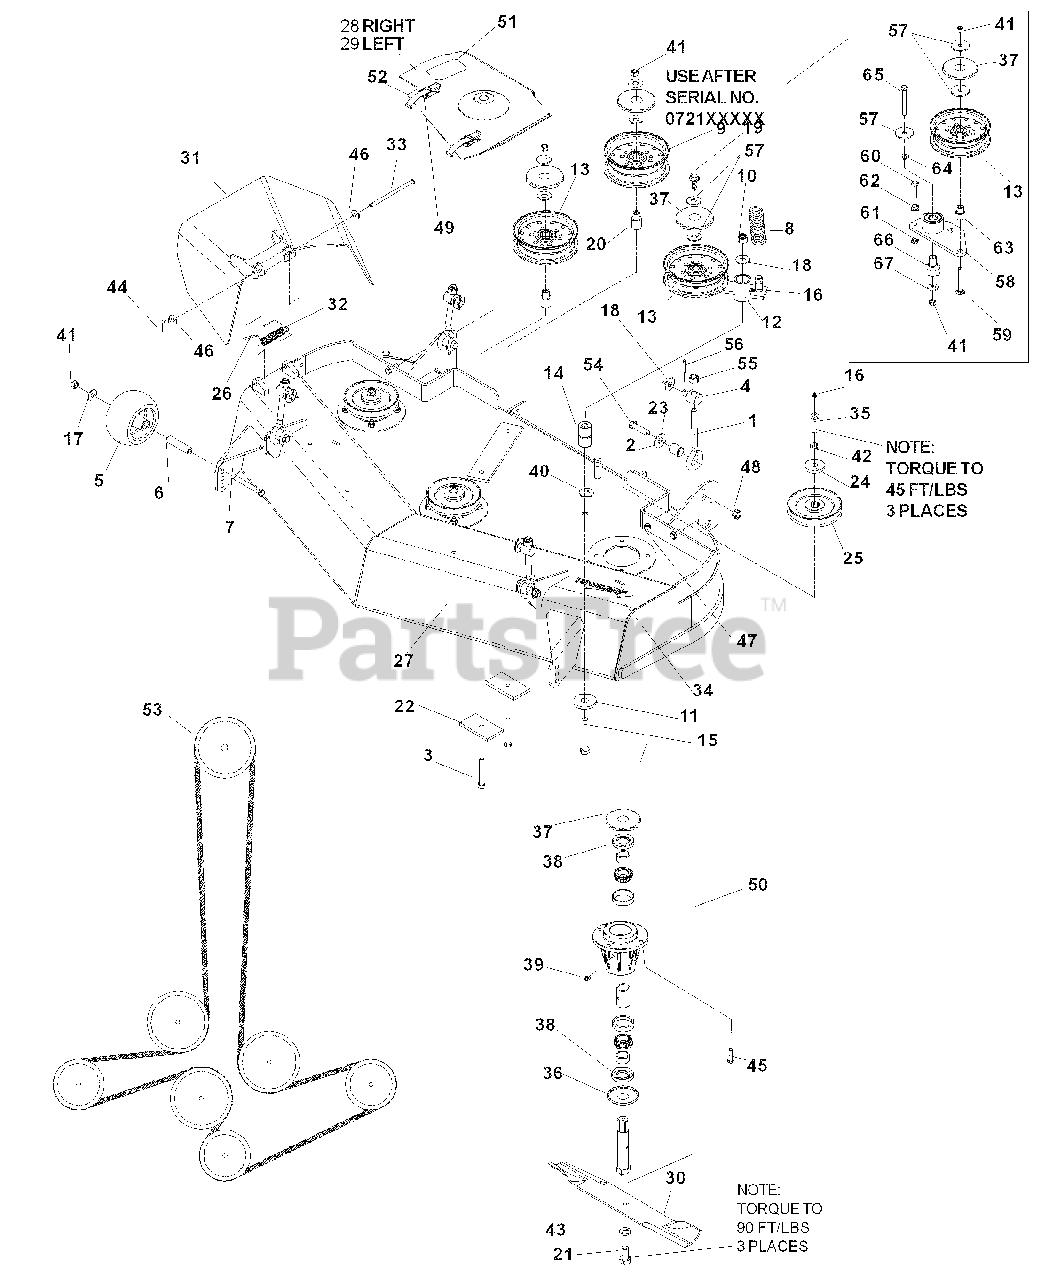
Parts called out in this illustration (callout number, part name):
3	HCS, 3/8-16 x 2 3/4
5	ROLLER, ANTI SCALP
7	HCS, 3/8-16 x 3 1/2, GR8
8	SPRING, EXTENSION
9	PULLEY, IDLER
10	NUT, 1/2-13, NYLOC
11	WASHER, .65
13	PULLEY, IDLER
14	BUSHING, PIVOT
15	HCS, 1/2-13 x 3 1/4
16	ZERK, STRAIGHT, 1/4-28
17	WASHER, 3/8
18	WASHER, 9/16
19	HCS, 3/8-16 x 1
20	BUSHING, IDLER
21	HCS, 5/8-18 x 1 1/4
22	PAD
23	SPRING WASHER, 1/2
24	WASHER, .469
25	PULLEY
26	CAP-SLEEVE
27	DECK W/DECALS
28	BELT SHIELD, RIGHT
29	BELT SHIELD, LEFT
30	BLADE, 14 5/8"
31	DISCHARGE CHUTE
32	SPRING, TORSION
33	PIN-CLEVIS, 5/16 DIA x 5.19
34	DECAL, TUNNEL RAM
35	HCS, 7/16-20 x 1 1/2, GR8
36	BOTTOM DUST CAP
37	TOP DUST CAP
38	SHAFT SEAL
39	PLUG, VENTED
40	WASHER, 1/2
41	NUT, 3/8-16, NYLOC
42	LOCKWASHER, 7/16
43	LOCKWASHER, 5/8
44	PIN COTTER, 1/8 x 3/4
45	HCS, 5/16-18 x 1 1/4
46	WASHER, 5/16
47	NUT, 5/16-18, NYLOC
48	NUT, 7/16-14, CNTRLCK, GR A
50	SPINDLE ASSEMBLY
51	DECAL, EURO SEVERING
52	DRAW LATCH
53	DECK BELT
54	HCS, 7/16-14 x 1 3/4
55	NUT, 1/2-13, NYLOC
56	PIN, COTTER, 1/8 x 1
57	WASHER, 3/8, SPEC
58	ARM, IDLER, W/BEARINGS
59	RHSNB, 3/8-16 x 2 3/4,
60	HCS, 3/8-16 x 1 1/2, GR8
61	NUT, 3/8-16, JAM
62	NUT, 3/8-16, WHIZLK
63	BUSHING, IDLER
64	WASHER, 3/8, SAE
65	HCS, 3/8-16 x 3
66	PIVOT, BEARING
67	WASHER, 3/8
